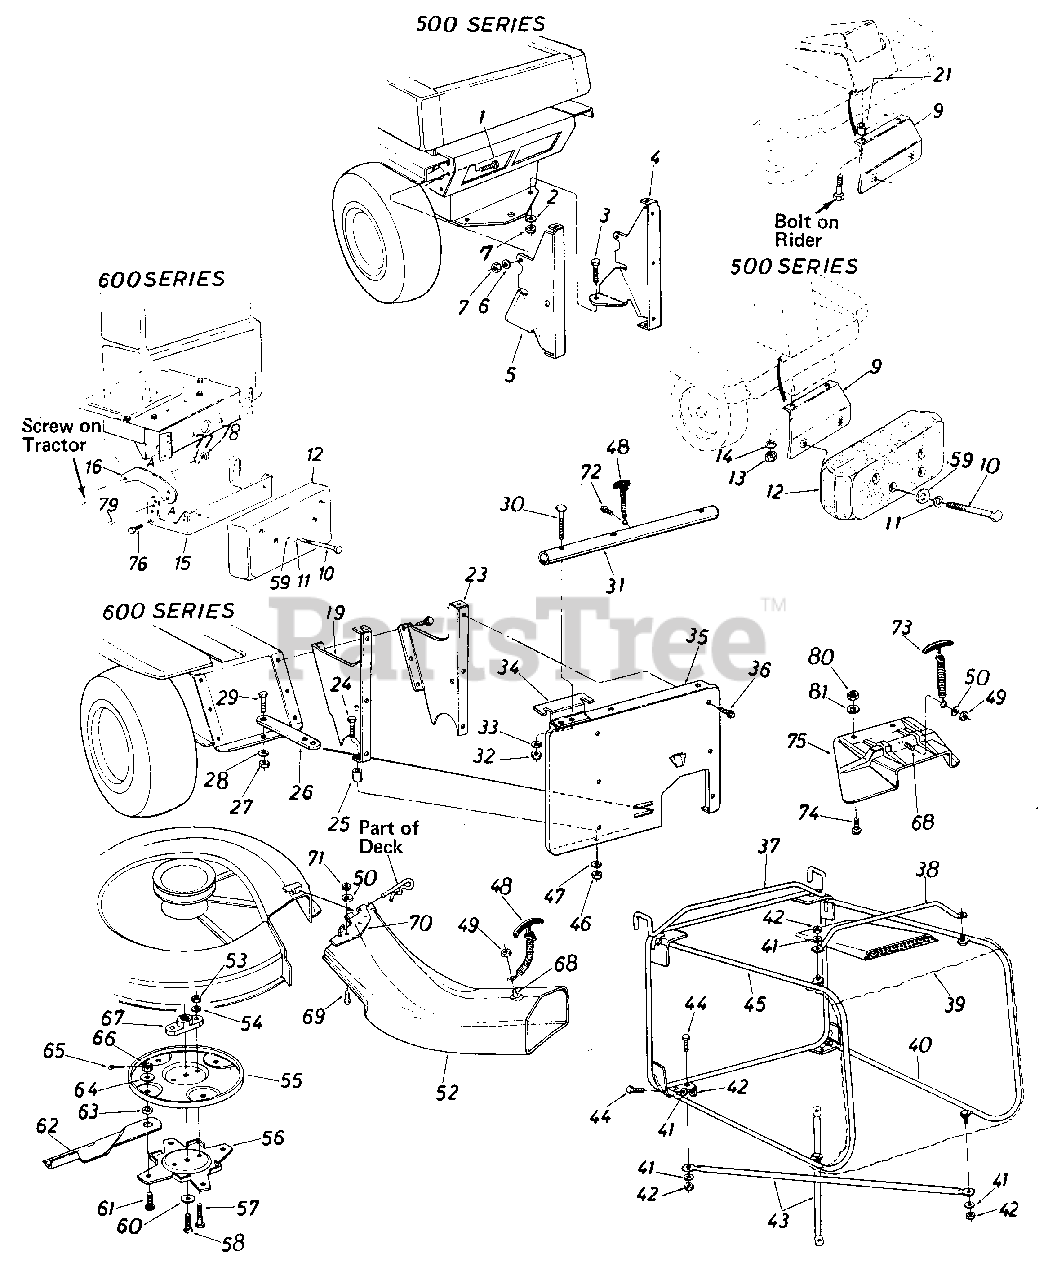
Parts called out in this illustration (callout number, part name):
1	SCREW-HEX 5/16-18 X 1.00
2	WASHER-LOCK-5/16
3	SCREW-HEX 5/16-18 X 1.00
4	BRACKET-SUPPORT-RH
5	BRACKET-SUPPORT-LH
6	WASHER-LOCK-5/16
7	NUT-HEX 5/16-18
9	BRACKET-SUPPORT
10	SCREW-HEX 3/8 X 4.5 N.C GR. 5
11	WASHER-BELL .400 ID X .88 X .060
12	COUNTERWEIGHT
13	NUT-HEX 5/16-18
14	WASHER-LOCK-5/16
15	BRACKET-WEIGHT
16	TIE-STRAP
19	BRACKET-SUPPORT-LH
23	BRACKET-SUPPORT-RH
24	SCREW-HEX 5/16-18 X 1.50
28	WASHER-LOCK-1/2
29	SCREW-HEX 1/2-13 X 1.00
30	BOLT-CARRIAGE 5/16-18 X 1.75
33	WASHER-LOCK-5/16
34	PLATE-SUPPORT
35	PANEL-RD
36	SCREW-HEX WASH SF TAPP
37	FRAME ASSY-CATCHER
42	NUT-HEX CENTER L-1/4-20
43	BRACE-BOTTOM
44	SCREW-HEX 1/4-20 C .62
47	WASHER-LOCK-5/16
48	LOCK ASSY-HOOD
49	NUT-HEX CENTER L-1/4-20
50	WASHER-FL-.281 ID X .50 OD X .063
52	CHUTE-BANANA-RD
53	NUT-5/16-24
54	WASHER-LOCK-5/16
55	DISC-BLADE
56	BLADE DISC-LOWER
57	SCREW-HEX SPECIAL 5/16-24X1.0
58	BOLT-3/8 NF X 1"GR5
59	WASHER-FL
60	WASHER-BELL .390 ID X 1.375 X .062
61	SCREW-SHLD .500X.360
62	BLADE TIP-30IN
64	WASHER-FL-.531 ID X 1.25 OD X 1.00
65	PIN-COTTER-3/32 DIA X 1.00
66	NUT-HEX SLOTTED-1/2-20
67	ADAPTER-BLADE
68	SCREW-HEX 1/4-20 X .50
69	SCREW-TRUSS MACH 1/4-20 X .50
70	BRACKET-MTG
71	NUT-HEX 1/4-20
72	SCREW-HEX WASH HD
73	LATCH ASSY-HOOD
74	SCREW-TRUSS MACH 1/4-20 X .50
75	EXTENSION-CHUTE-RD
76	SCREW-HEX 7/16-20 X 1.00
77	WASHER-LOCK-7/16
78	NUT-JAM 7/16-20
79	SCREW-HEX AB-TAP
80	NUT-HEX CENTER L-1/4-20
81	WASHER-FL-.281 ID X .50 OD X .063
